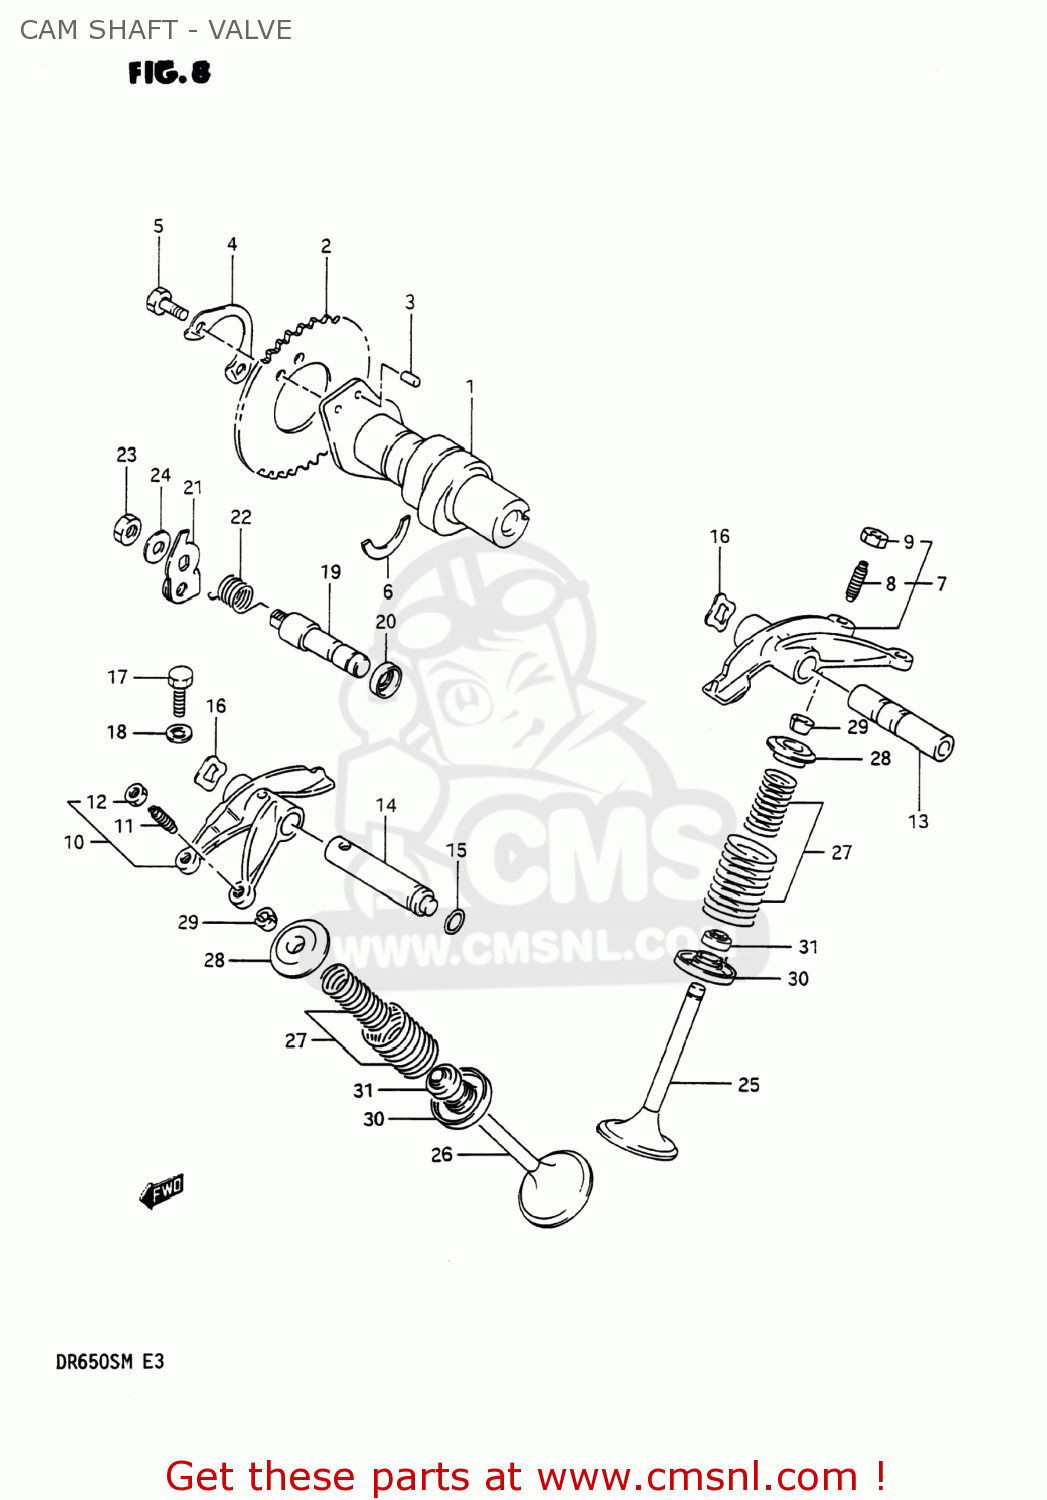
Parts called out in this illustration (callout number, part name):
1	CAMSHAFT
2	SPROCKET,CAMSHAFT(NT:42)
3	PIN
4	WASHER,CAM CHAIN SPROCKET
5	BOLT(6X12.5)
6	C RING
7	ARM,VALVE ROCKER INTAKE
8	SCREW,TAPPET ADJUSTING
9	NUT,ADJUSTING SCREW
10	ARM,VALVE ROCKER EXHAUST
11	SCREW,TAPPET ADJUSTING
12	NUT,ADJUSTING SCREW
13	SHAFT,VALVE ROCKER ARM INTAKE
14	SHAFT,EXHAUST VALVE ROCKER ARM
15	O RING(D:1.9,ID:8.6)
16	WASHER
17	BOLT 6X30
18	GASKET(5.8X13X1.2) (NAS)
19	SHAFT,DECOMPRESSION
20	SEAL,OIL(10X17X6)
21	LEVER,DECOMP SHAFT
22	SPRING,DECOMPRESSION SHAFT LEVER
23	NUT 8MM
24	WASHER
25	VALVE,INTAKE
26	VALVE,EXHAUST
27	SPRING SET,VALVE
28	RETAINER,VALVE SPRING
29	COTTER VALVE
30	SEAT,VALVE SPRING
31	SEAL,OIL(7X14.4X9)
